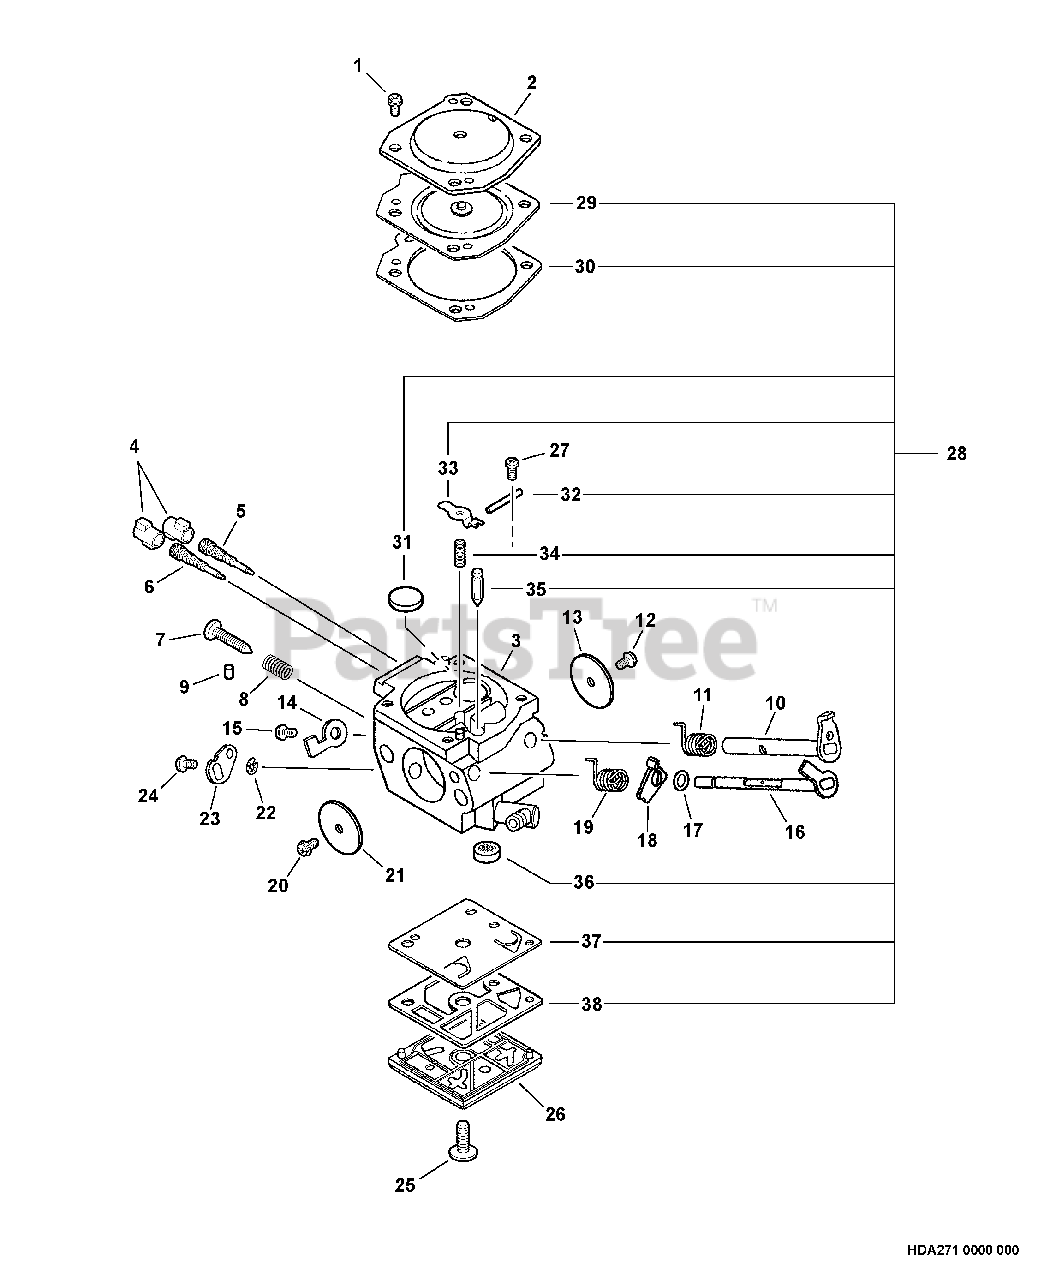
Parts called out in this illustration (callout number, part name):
2	COVER, METERING DIAPHRAGM
3	BODY, CARBURETOR
4	CAP, LIMITER
5	NEEDLE, MIXTURE
6	NEEDLE, HIGH SPEED
7	SCREW, IDLE ADJUST
9	PLUG, FRICTION
10	SHAFT ASSY, THROTTLE
11	SPRING, THROTTLE RETURN
13	VALVE, THROTTLE
14	STOP, THROTTLE
16	SHAFT ASSY, CHOKE
18	LEVER, FAST IDLE
19	SPRING, CHOKE RETURN
21	VALVE, CHOKE
23	LEVER, CHOKE
26	COVER, FUEL PUMP
27	SCREW, METERING LEVER PIN
28	REPAIR KIT
29	DIAPHRAGM, METERING
30	GASKET, DIAPHRAGM
31	PLUG, WELCH
32	PIN, METERING LEVER
33	LEVER, METERING
34	SPRING, METERING LEVER
35	VALVE, INLET NEEDLE
36	STRAINER
37	DIAPHRAGM, PUMP
38	GASKET, PUMP
